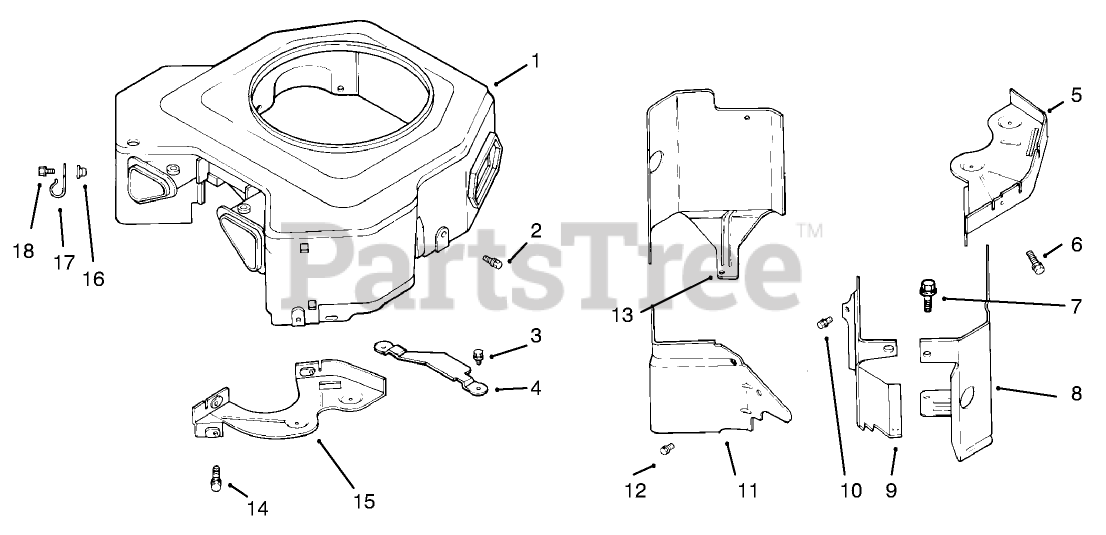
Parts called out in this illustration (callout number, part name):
1	Housing-Blower ASM (Only C)n: 72103, 72083)
2	Screw
3	Screw
4	Guard-Flywheel (Only On: 72103, 72083)
5	Plate-Backing #2 side
6	Screw
7	Screw
8	Baffle Cylinder #2 Side
9	Baffle-Valley #1 Side (Only On: 72103)
10	Screw
11	Baffle-Valley #2 Side (Only On: 72103, 72083)
12	Screw
13	Baffle-Cylinder #1 Side (Only On: 72103)
14	Screw
15	Plate-Backing #1 Side (Only On: 72103, 72083)
16	Nut
17	Clip-Cable (Only On: 72103)
18	Screw
